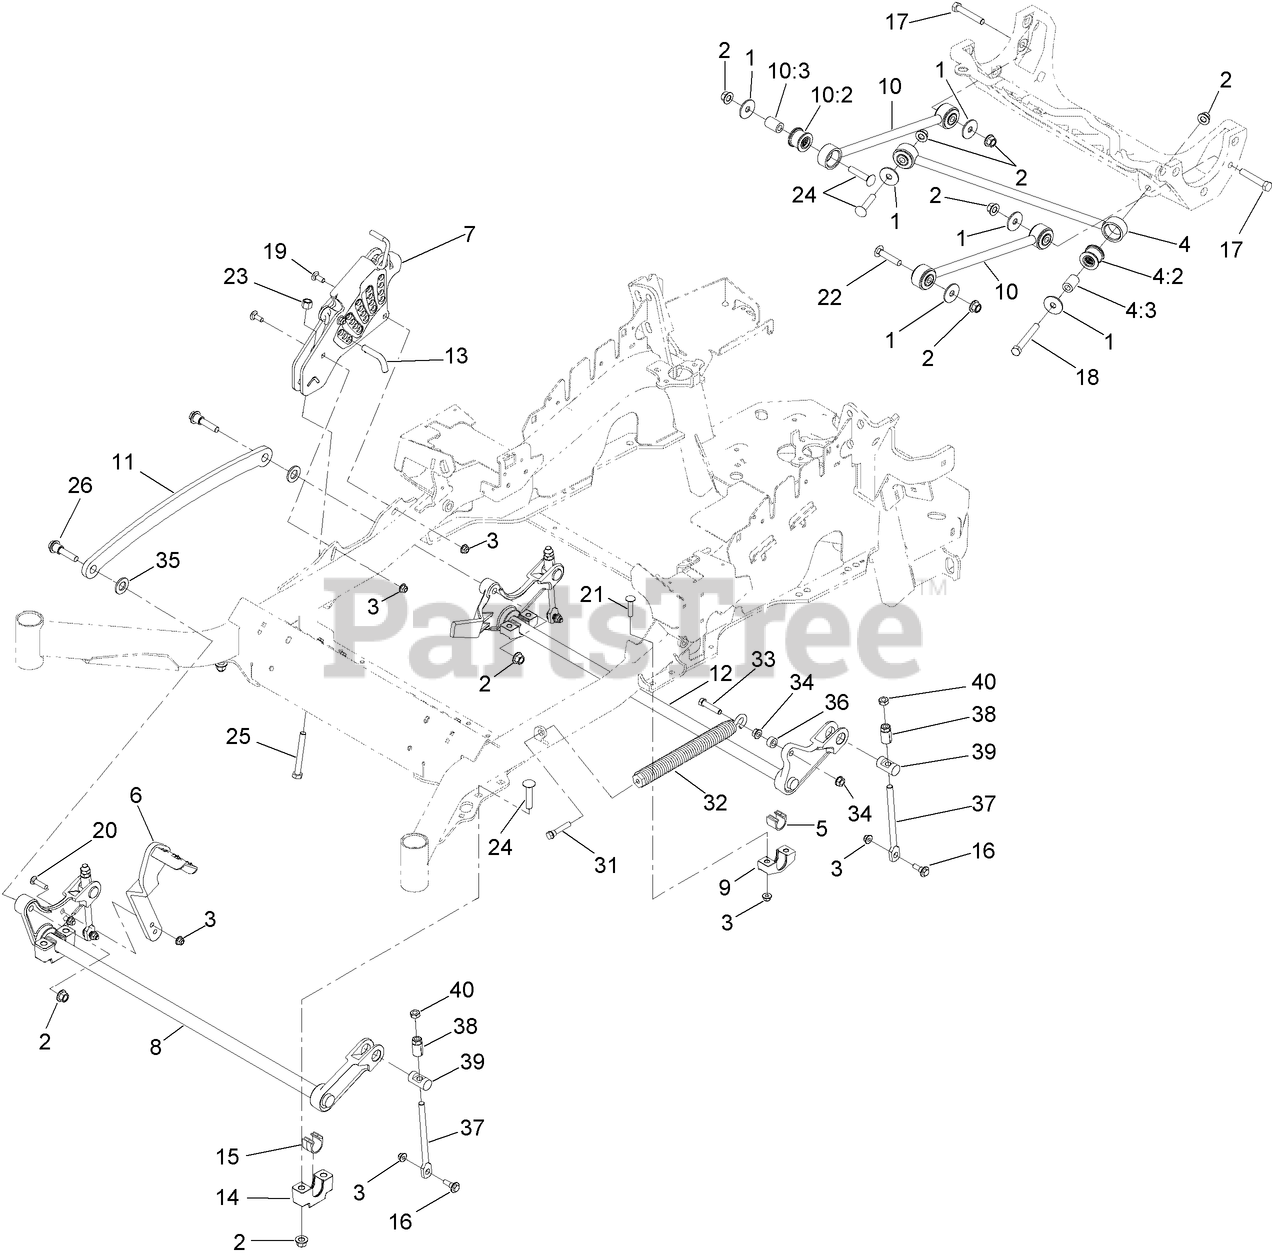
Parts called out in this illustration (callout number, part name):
1	WASHER-THRUST
2	NUT-LOCK
3	NUT-HF, NI
4	PANHARD ROD ASM
4:2	BUSHING-SUSPENSION, RUBBER
4:3	SPACER
5	BEARING-CROSS SHAFT, REAR
6	LEVER-FOOT
7	HOC ASM
8	DECK LIFT-FRONT
9	SUPPORT-CROSS SHAFT, REAR BEARING
10	DECK STRUT ASM
10:2	BUSHING-SUSPENSION, RUBBER
10:3	SPACER
11	LINK-LIFT, DECK
12	LIFT-DECK, REAR
13	PIN-HOC
14	SUPPORT-CROSS SHAFT, BEARING
15	BEARING-CROSS SHAFT, FRONT
16	SCREW-SHOULDER, HHF
17	SCREW-HH
18	SCREW-HH
19	BOLT-CARR
20	SCREW-CARR
21	SCREW-CARR
22	SCREW-CARR
23	NUT-LOCK, NI
24	BOLT-CARR
25	BOLT-TAP
26	SCREW-HHF, SHOULDER
31	BOLT-SHOULDER
32	SPRING-EXTENSION
33	SCREW-HH
34	NUT-HF
35	WASHER-FLAT
36	SPACER
37	LINK-ADJUSTER, DECK LIFT
38	ADJUSTER-LIFT, DECK
39	TRUNNION
40	NUT-JAM
